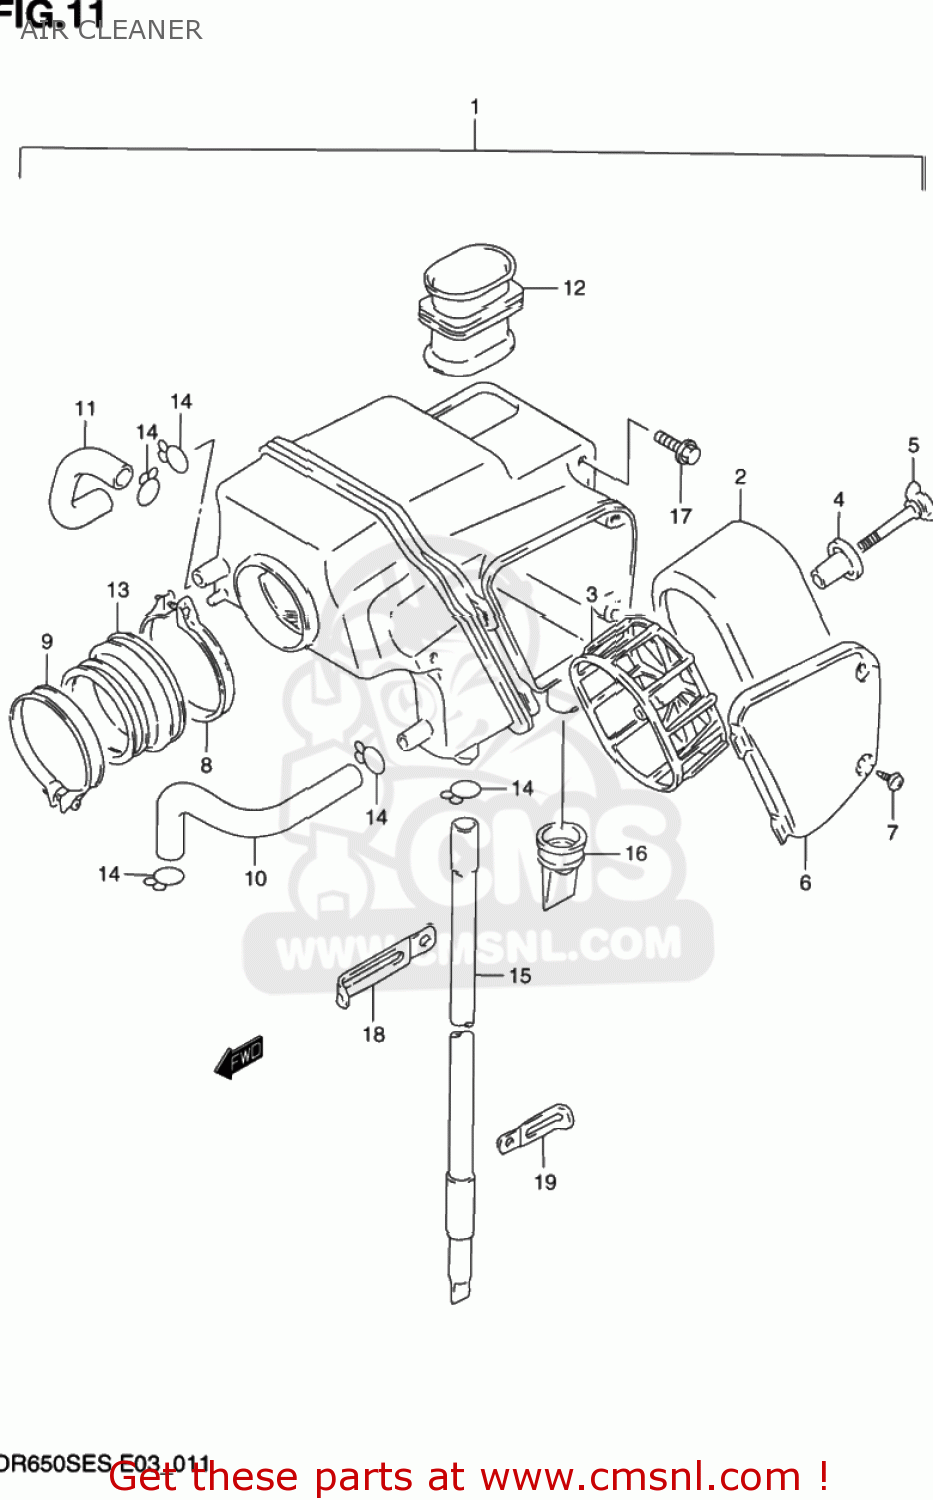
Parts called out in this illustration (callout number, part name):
1	CLEANER ASSY,AIR
2	FILTER
3	HOLDER,FILTER
4	SPACER
5	BOLT,WING
6	CAP,AIR CLEANER
7	SCREW
8	CLAMP
9	CLAMP
10	TUBE,BREATHER
11	TUBE,CONNECTING
12	TUBE,INLET
13	TUBE,OUTLET
14	CLIP
15	DRAIN TUBE
16	CAP,DRAIN
17	BOLT(6X14)
18	CLAMP
19	CLAMP
